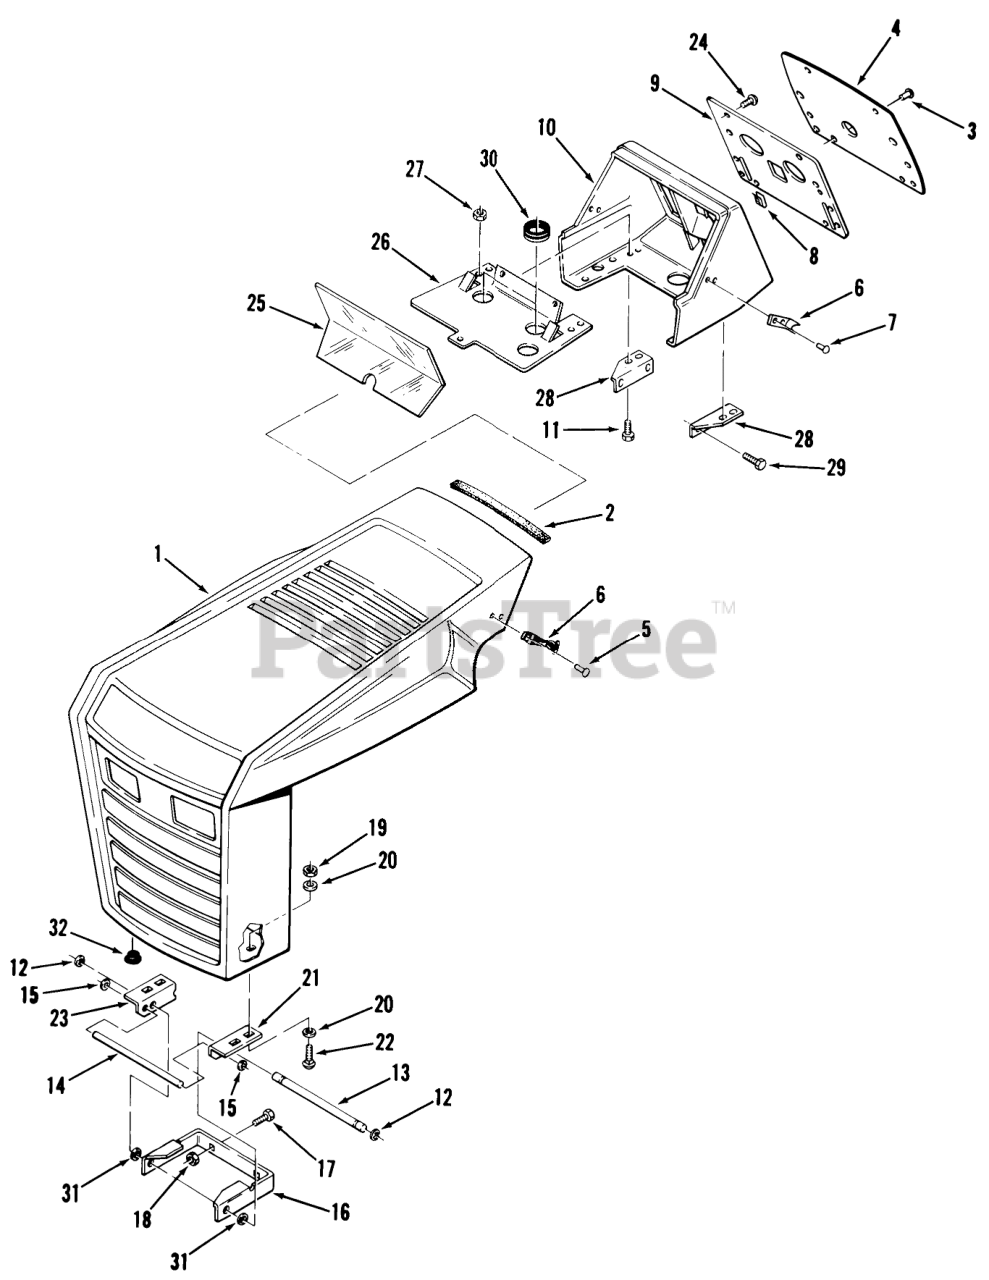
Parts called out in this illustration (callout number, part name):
2	TRIM-CONSOLE
3	RIVET-4
4	PLATE-INSTRUMENT
5	RIVET
6	ASSY-FLEX DRAW LATCH
7	RIVET
8	SPEED NUT
9	Back-Up Plate
10	Console
11	Screw
12	RING-RETAINING
13	ROD-GRILL PIVOT
14	ROD-HOOD STOP
15	SPEED NUT
16	Bracket-Hood Pivot
17	Bolt-Carriage
18	Nut
19	Nut
21	BRKT-HOOD PIVOT LH
22	Bolt-Carriage
23	Pivot Bracket Hood RH
24	SCREW BLACK
25	CONTROL PROTECTOR
26	Support-Fuel Tank
27	Nut
28	Bracket-Console RH
28	Bracket-Console LH
29	HEX WASH HD SCREW
30	Grommet
32	GROMMET
